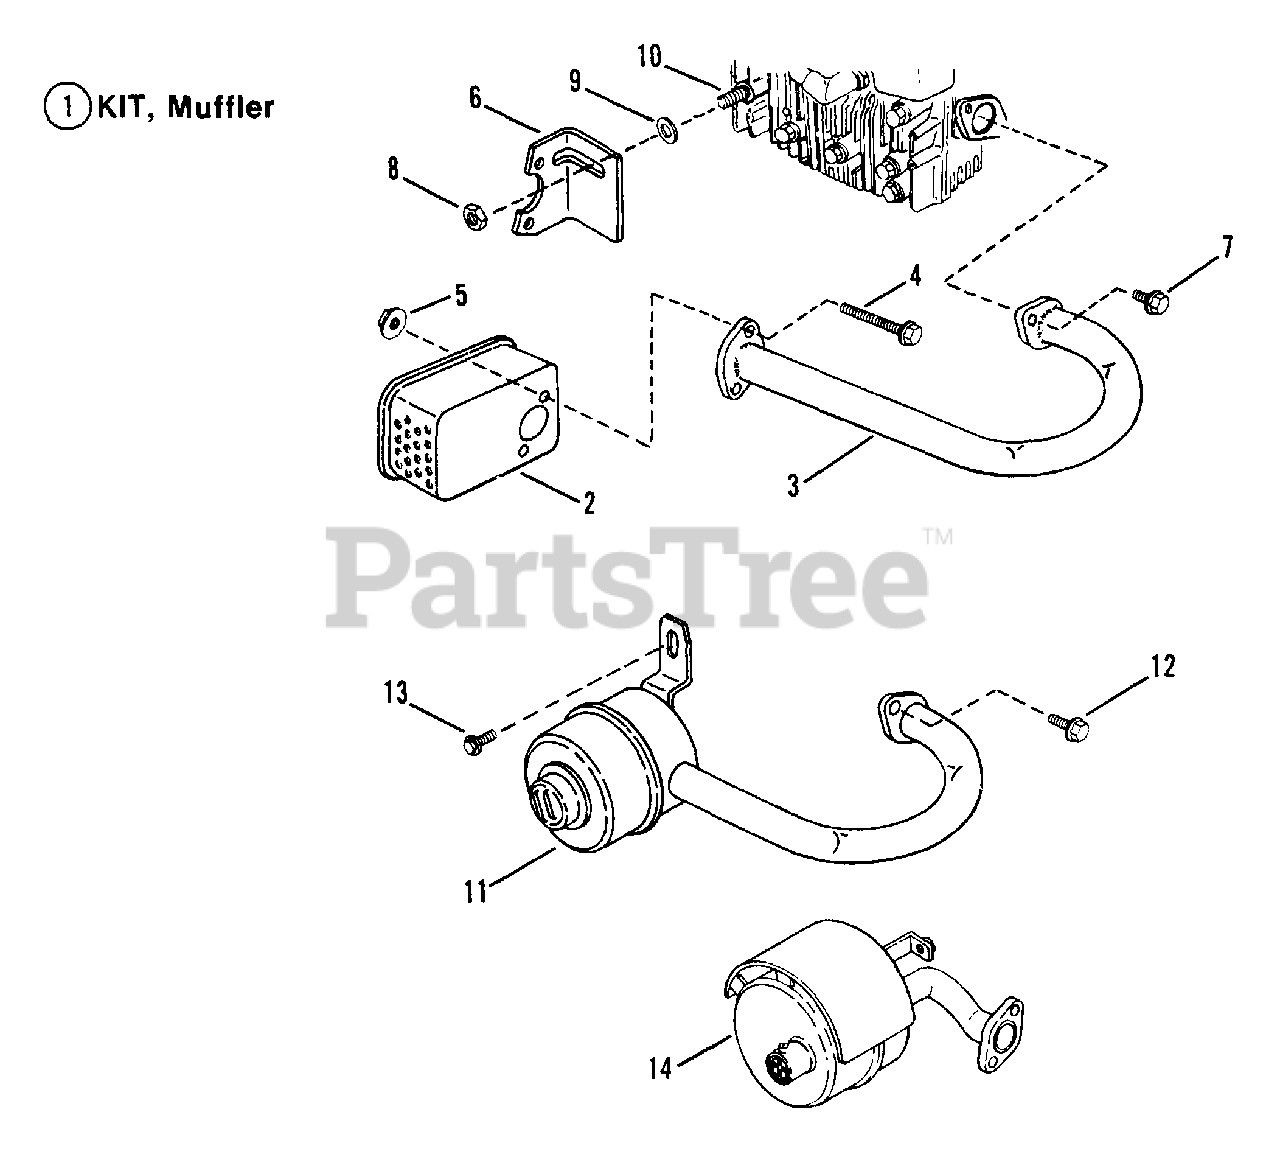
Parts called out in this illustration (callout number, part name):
1	KIT, Muffler
2	MUFFLER
3	TUBE, Exhaust
4	SCREW, 5/16-18 x 3" Hex Head Cap
5	NUT, 5/16-18 Hex Flange Lock
6	BRACKET, Muffler
7	SCREW, 1/4-20 x 5/8" Hex Head Cap
8	NUT, 5/16-18 Hex
9	WASHER, Flat
10	STUD, Cylinder Head
11	MUFFLER
12	SCREW, 5/16-18 x 3/4" Hex Head Cap
13	SCREW, 1/4-20 x 3/4" Hex Head Cap
14	MUFFLER
